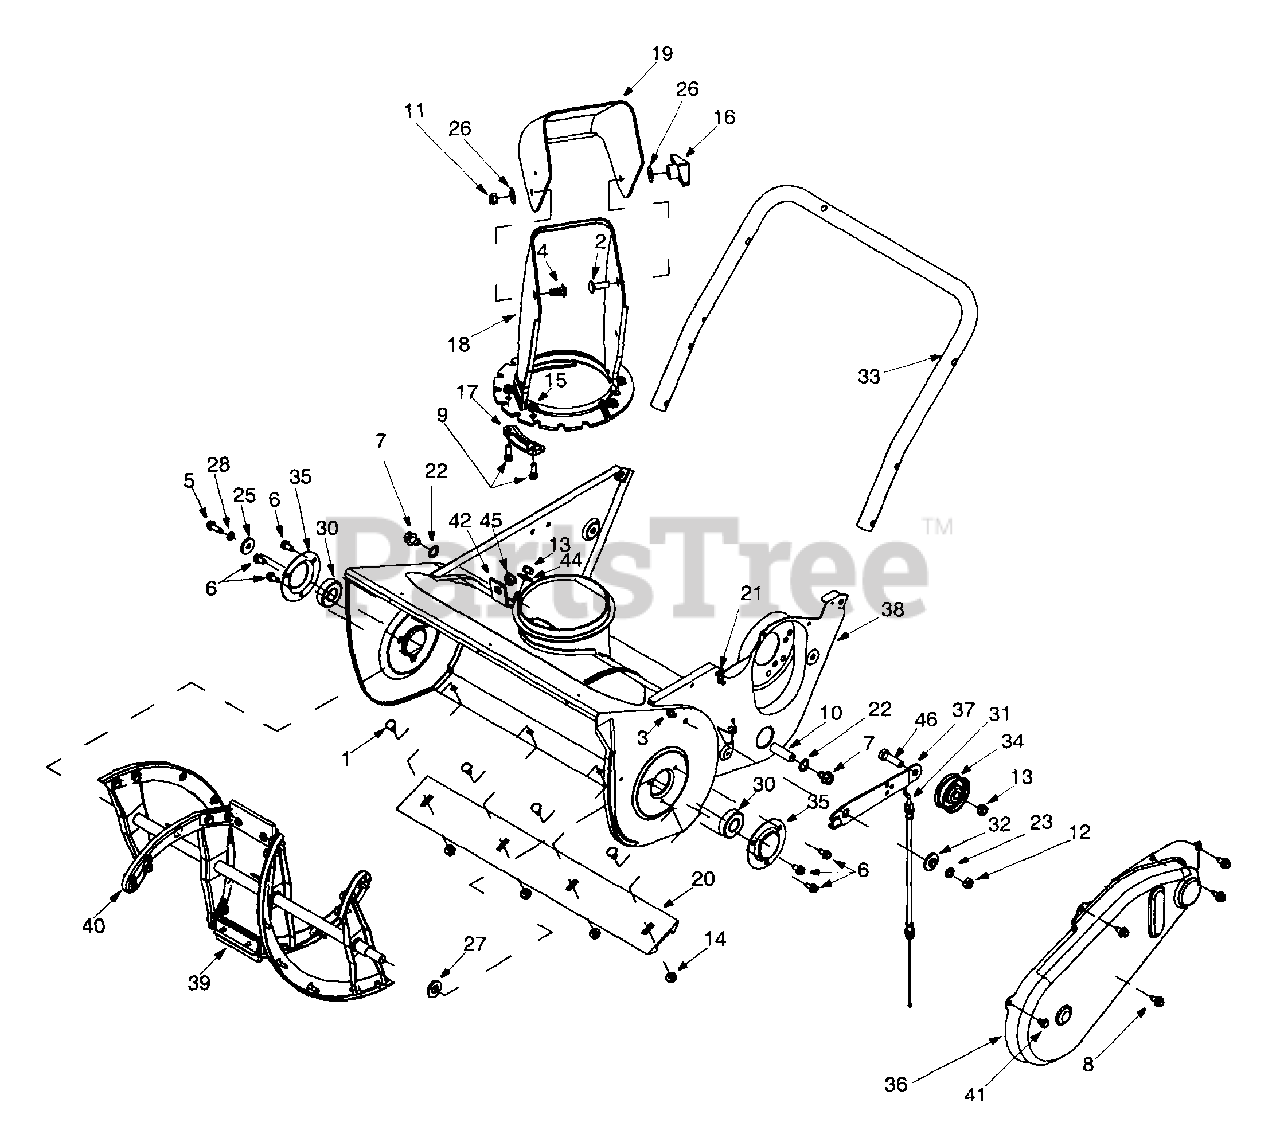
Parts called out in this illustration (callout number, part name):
1	Carriage Bolt
2	Carriage Bolt
3	Pan Head Screw
4	Carriage Bolt
5	Hex Washer Screw
6	Hex Washer Screw
7	Hex Washer Screw
8	Hex Washer Screw
9	Hex Cap Screw
10	Axle
11	Hex Center Lock Nut
12	Hex Nut
13	Hex Lock Nut
14	Hex Lock Flanged Nut
15	Hex Lock Flanged Nut
17	Chute Keeper
18	Lower Chute
19	Upper Chute
20	Shave Plate
21	Extension Spring
22	Flat Washer
23	Lock Washer
25	Flat Washer
26	Washer
27	Flat Washer
28	Lock Washer
30	Ball Bearing
31	Cable-Clutch
32	Spacer
37	Idler/Brake Bracket
40	Auger Rubber Replacement
41	Hex Washer Screw
44	Bell Washer
45	Bushing
46	Hex Screw
